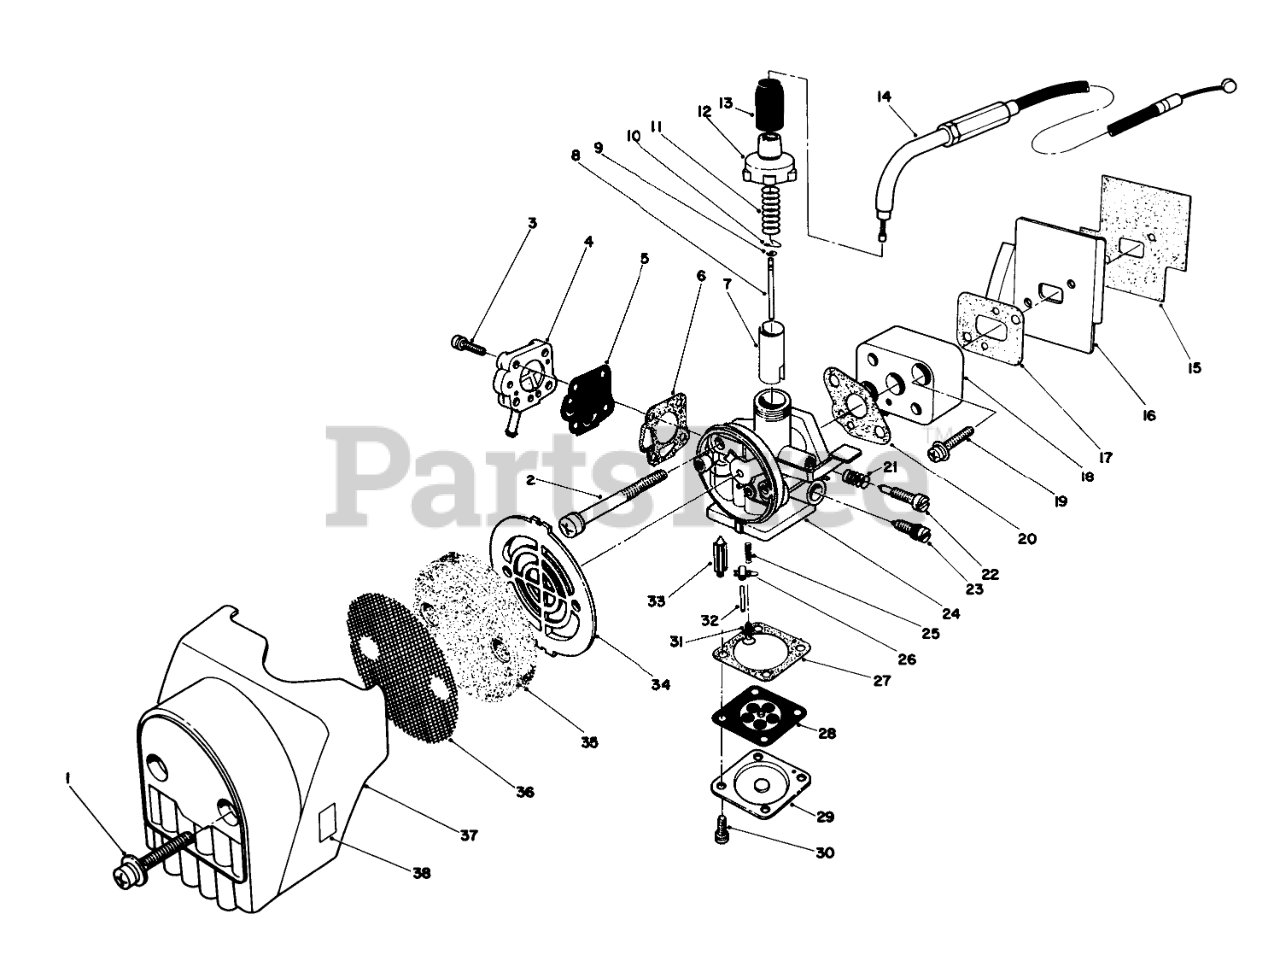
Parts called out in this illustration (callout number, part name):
1	Screw
2	SCREW W/ WASHER
3	SCREW W/ WASHER
4	PUMP COVER
5	PUMP DIAPHRAGM
6	PUMP COVER GASKET
7	Valve-Throttle
8	NEEDLE JET
9	Retainer
10	NEEDLE CUP
11	SPRING
13	AIR SEAL
14	Wire-Throttle
15	Gasket
16	Plate
17	INSULATOR GASKET
18	Insulator
19	Screw
20	CARB. GASKET
21	ADJ. SCREW SPRING
22	Screw-Adjusting
23	MAIN NEEDLE
24	Carburetor Assembly (Incl. Ref. #3-13, 21-23, & 25-33)
25	VALVE SPRING
26	FLOAT ARM
27	DIAPHRAGM GASKET
28	MAIN DIAPHRAGM
29	DIAPHRAGM COVER
30	SCREW W/ WASHER
31	FLOAT SCREW
32	FLOAT PIN
33	FLOAT VALVE
35	ELEMENT
36	SCREEN
37	CLEANER COVER
38	CHOKE LABEL
